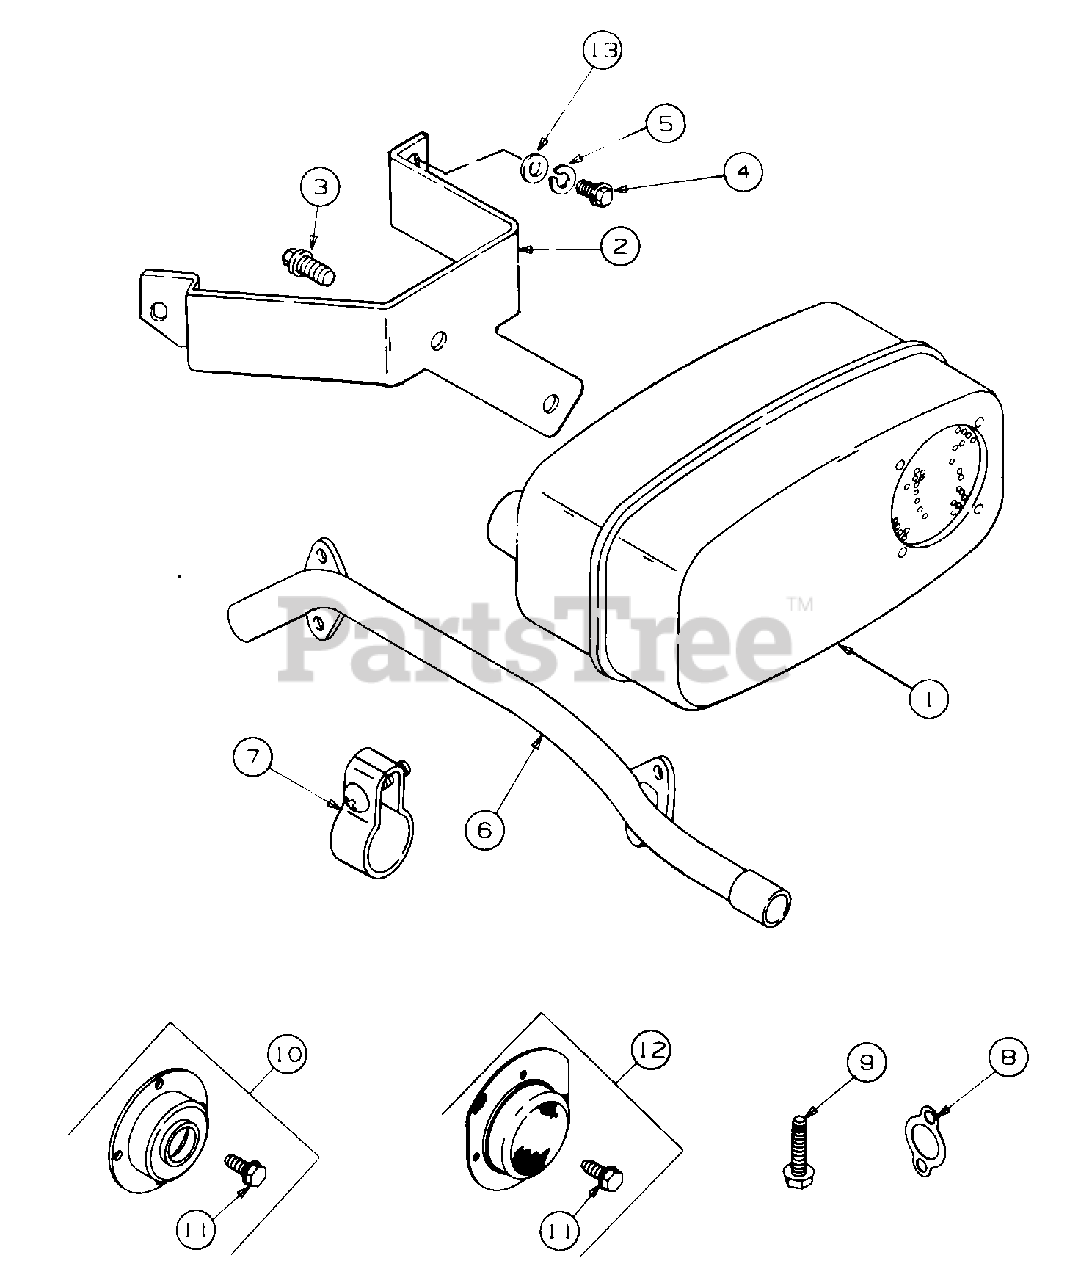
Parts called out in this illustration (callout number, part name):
1	Muffler
2	Bracket, Muffler
3	Screw, Hex Wash Hd Tap, 1/4-20 X .50 Lg
4	Screw, Hex Cap, M6-1.0 X 20 mm Lg GR10.9
5	Washer, Lock, 1/4
6	Manifold, Exhaust
7	Clamp, Muffler
8	Gasket, Exhaust Manifold
9	Screw, Sem
10	Deflector, Exhaust
11	Screw, Sem
12	Arrester, Spark
13	Washer, Flat, .281 X .75 X .105 Thk
